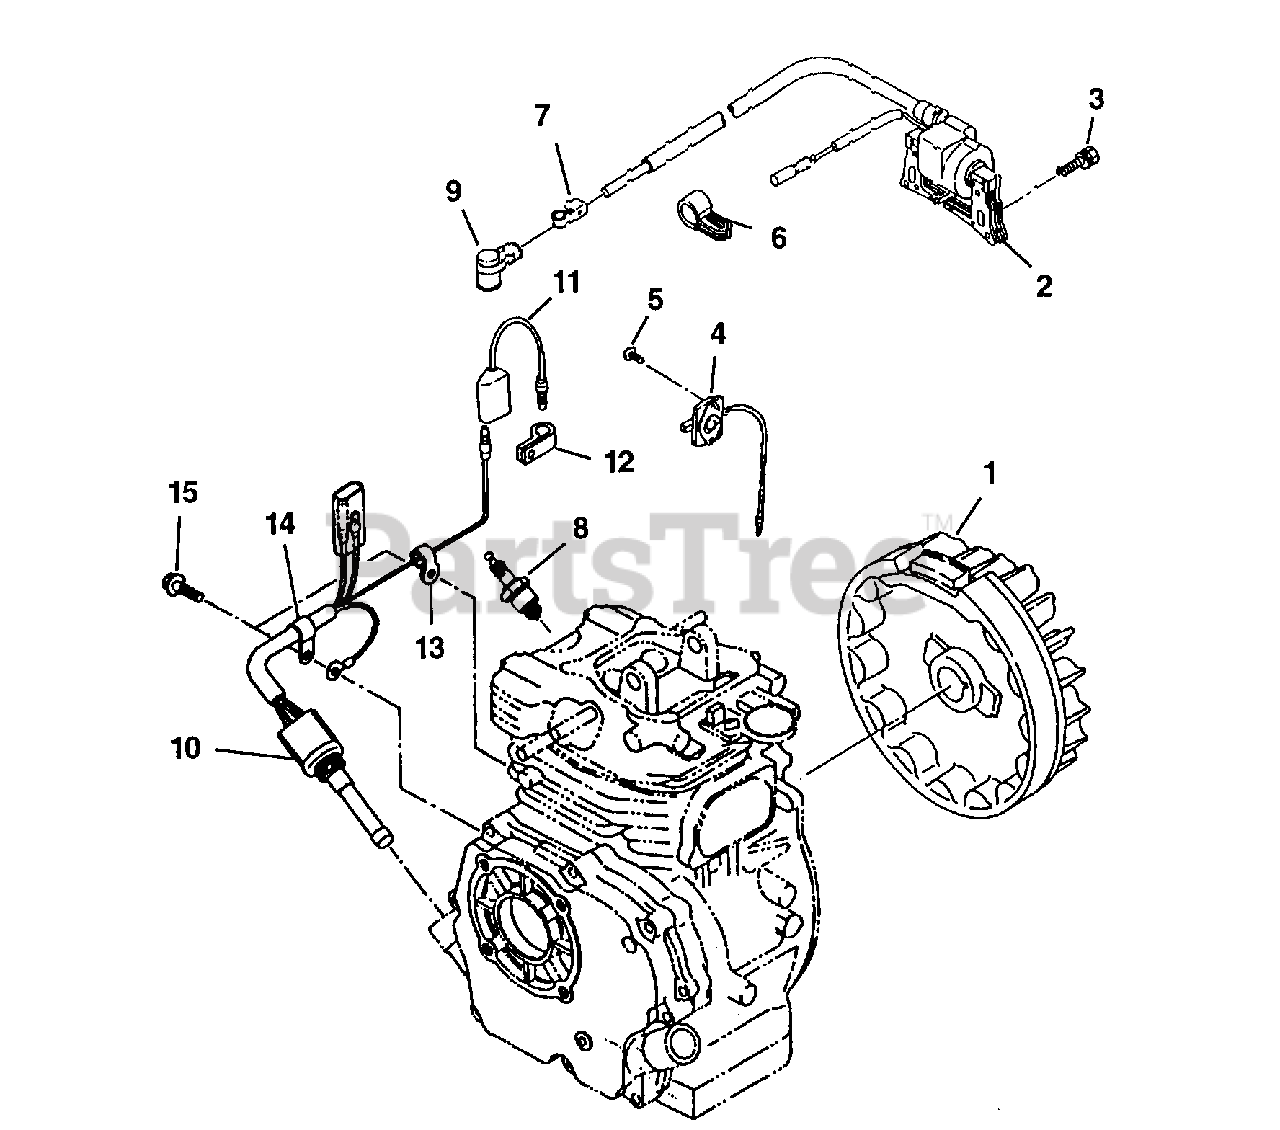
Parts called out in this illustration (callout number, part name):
1	Flywheel
2	Ignition coil
3	Bolt & washer M6 X 1.0 X 25L
4	Switch assy
5	Tapping screw M4 X 07 X 8L
7	Plug terminal
8	Spark plug
9	Spark plug cap
10	Oil sensor
15	Bolt & washer
